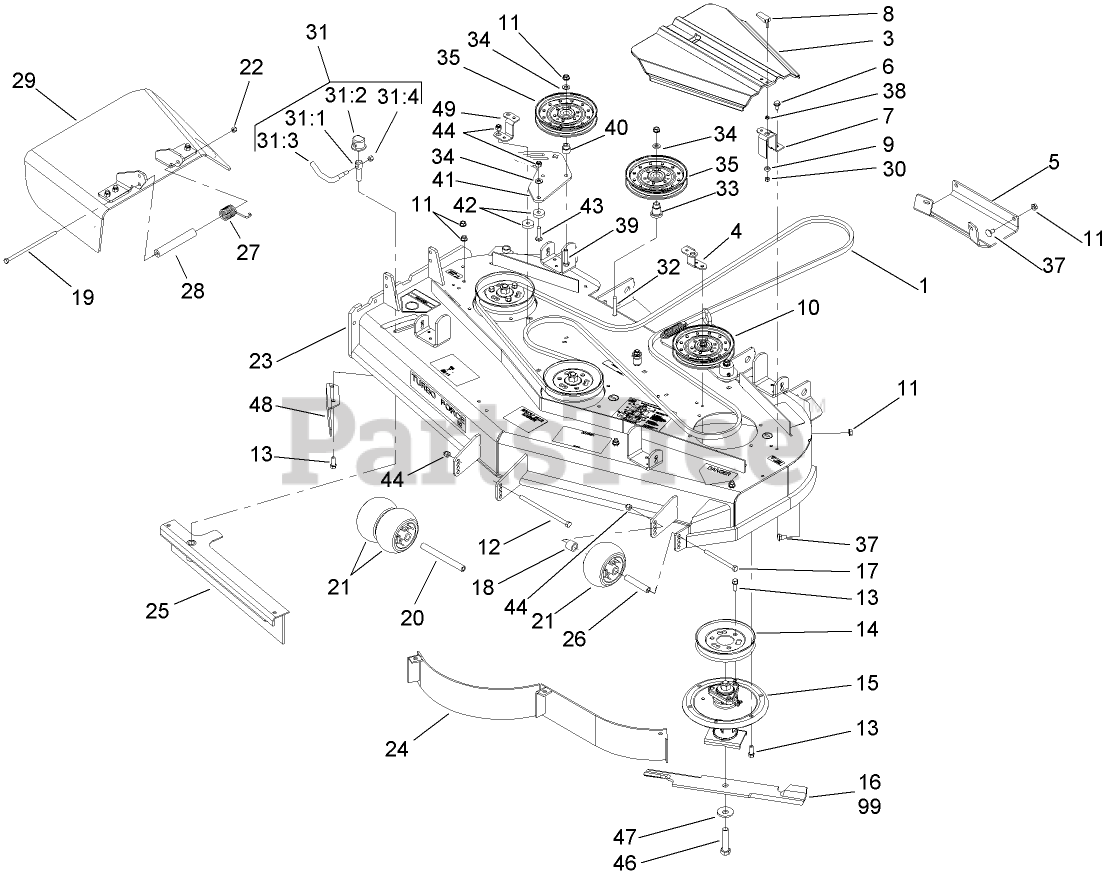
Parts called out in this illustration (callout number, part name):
1	BELT-V
3	COVER-BELT
4	BRACKET-COVER, TALL
5	Plate-Skid
6	SCREW-HWHTF
7	BRACKET-COVER
8	HANDLE-LATCH, SWELL
9	BUSHING-LATCH, SWELL
10	SPRING IDLER ASM
11	NUT-HHF, WHIZ
12	SCREW-HH
13	SCREW-HWH
14	PULLEY
15	SPINDLE ASM
16	BLADE-18IN, HI FLOW
17	SCREW-HH
18	TUBE-SPACER
19	SCREW-HH
20	SPACER-WHEEL
21	ROLLER-SCALP, ANTI
22	NUT-LOCK, NI
23	DECK ASM
26	TUBE-SPANNER
27	SPRING-TORSION
28	SPACER
29	RUBBER DEFLECTOR ASM
30	NUT-LOCK, HH
31	LEVER ASM
31:1	Screw-Lock
31:2	CAP-LOCK
31:3	Lever-Lock
31:4	NUT-LOCK, NI
32	SCREW-CARR
33	MOUNT-PULLEY
34	WASHER-FLAT
35	Idler-Flat
37	SCREW-CARR
38	WASHER
39	SCREW-HH
40	BUSHING-IDLER
41	PLATE-IDLER
42	Spacer
43	SCREW-CARR
44	NUT-LOCK, NI
46	Screw-Cap
47	Washer-Blade Bolt, Heavy
48	BAFFLE-DISCHARGE
49	BRACKET-COVER, SHORT
99	BLADE-ATOMIC
99	BLADE-LOW FLOW
99	BLADE-MED FLOW
99	BLADE-RECYCLER
